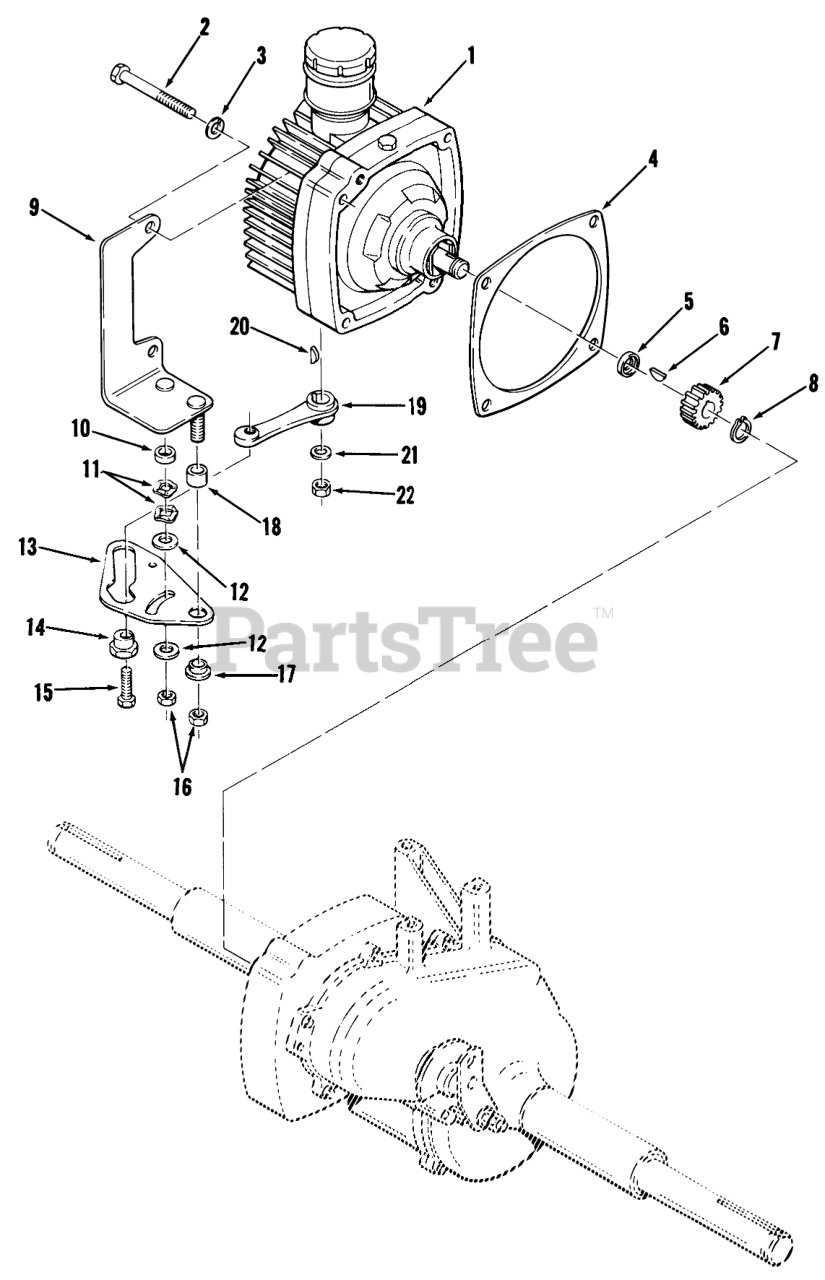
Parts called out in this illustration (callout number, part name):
1	Pump & Motor
2	Screw-Hex. Hd.
3	LOCKWASHER
4	GASKET HYDRO
5	SPACER-GEAR
6	KEY WOODR 1/8X1/2 DI
7	Gear 12 Tooth
8	SNAP RING
9	ASSY CONTROL SUPP R
10	SPACER-FRICTION
11	WASHER-SPRING DISC
12	FRICTION WASHER
13	CAM-SPEED CONTROL (NS)
15	Bolt
17	CAM-SPACER
18	SPACER-PIVOT
19	ARM-SPEED CONTROL
20	KEY WOODR 1/8X1/2 DI
21	Washer
22	Nut
